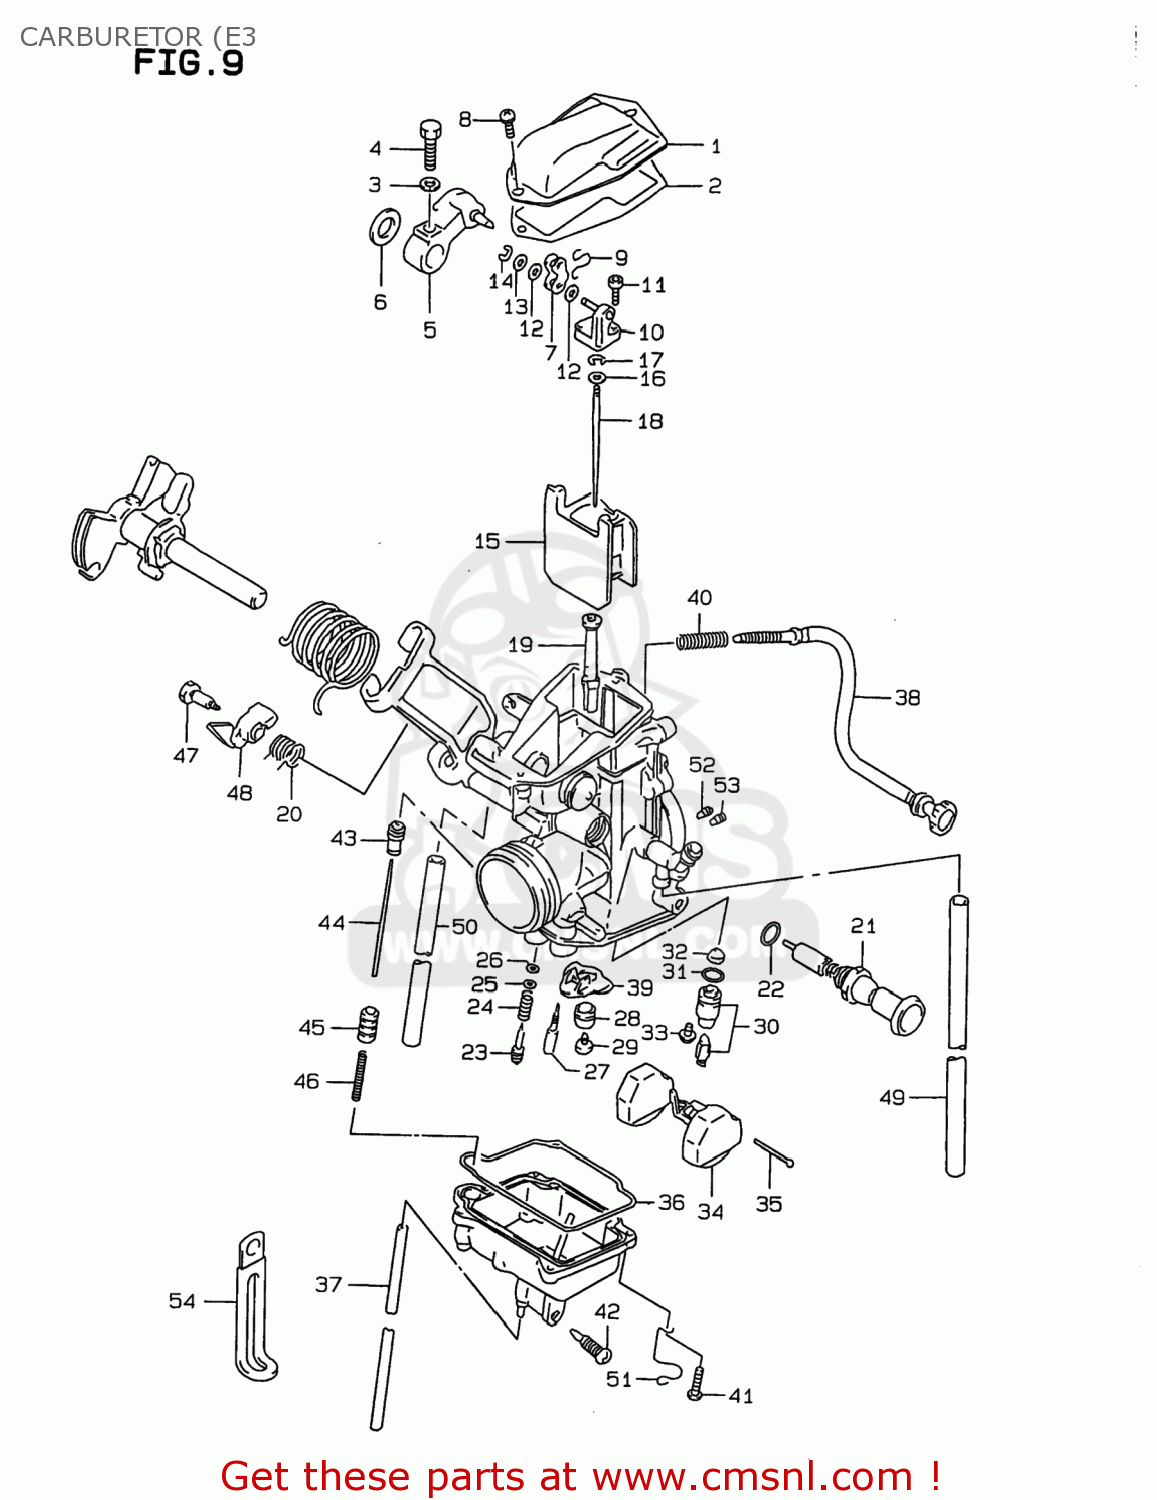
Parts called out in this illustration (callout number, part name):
1	COVER,CARBURETOR,TOP
2	GASKET,CARBURETOR TOP (NAS)
3	LOCK,WASHER
4	BOLT
5	LEVER SET,THROTTLE
6	RING,THROTTLE SHAFT
7	PLATE
8	SCREW
9	SPRING
10	CONNECTOR
11	SCREW
12	GASKET (NAS)
13	WASHER
14	E RING
15	VALVE,PISTON
16	WASHER,JET NEEDLE
17	CLIP
18	NEEDLE,JET
19	JET,NEEDLE(P-8)
20	SPRING
21	PLUNGER ASSY
22	O RING
23	SCREW,PILOT
24	SPRING
25	WASHER
26	O RING,PILOT AIR SCREW
27	JET,PILOT(37.5)
28	RING,MAIN JET FIXING
29	JET,MAIN(127.5)
30	VALVE ASSEMBLY,NEEDLE
31	O-RING,NEEDLE VALVE
32	FILTER
33	SCREW
34	FLOAT
35	PIN,FLOAT
36	O RING,FLOAT CHAMBER
37	HOSE(3X5X600)
38	ADJUSTER ASSY
39	RING
40	SPRING
41	SCREW
42	SCREW,DRAIN
43	BOOT, ACCELE PUMP ROD
44	ROD
45	PLUNGER
46	SPRING
47	BOLT
48	LEVER
49	HOSE(5X9X600)
50	HOSE(5X9X600)
51	CLIP
52	JET,MAIN AIR(0.7)
53	JET,AIR(1.1)
54	CLAMP(L:45)
